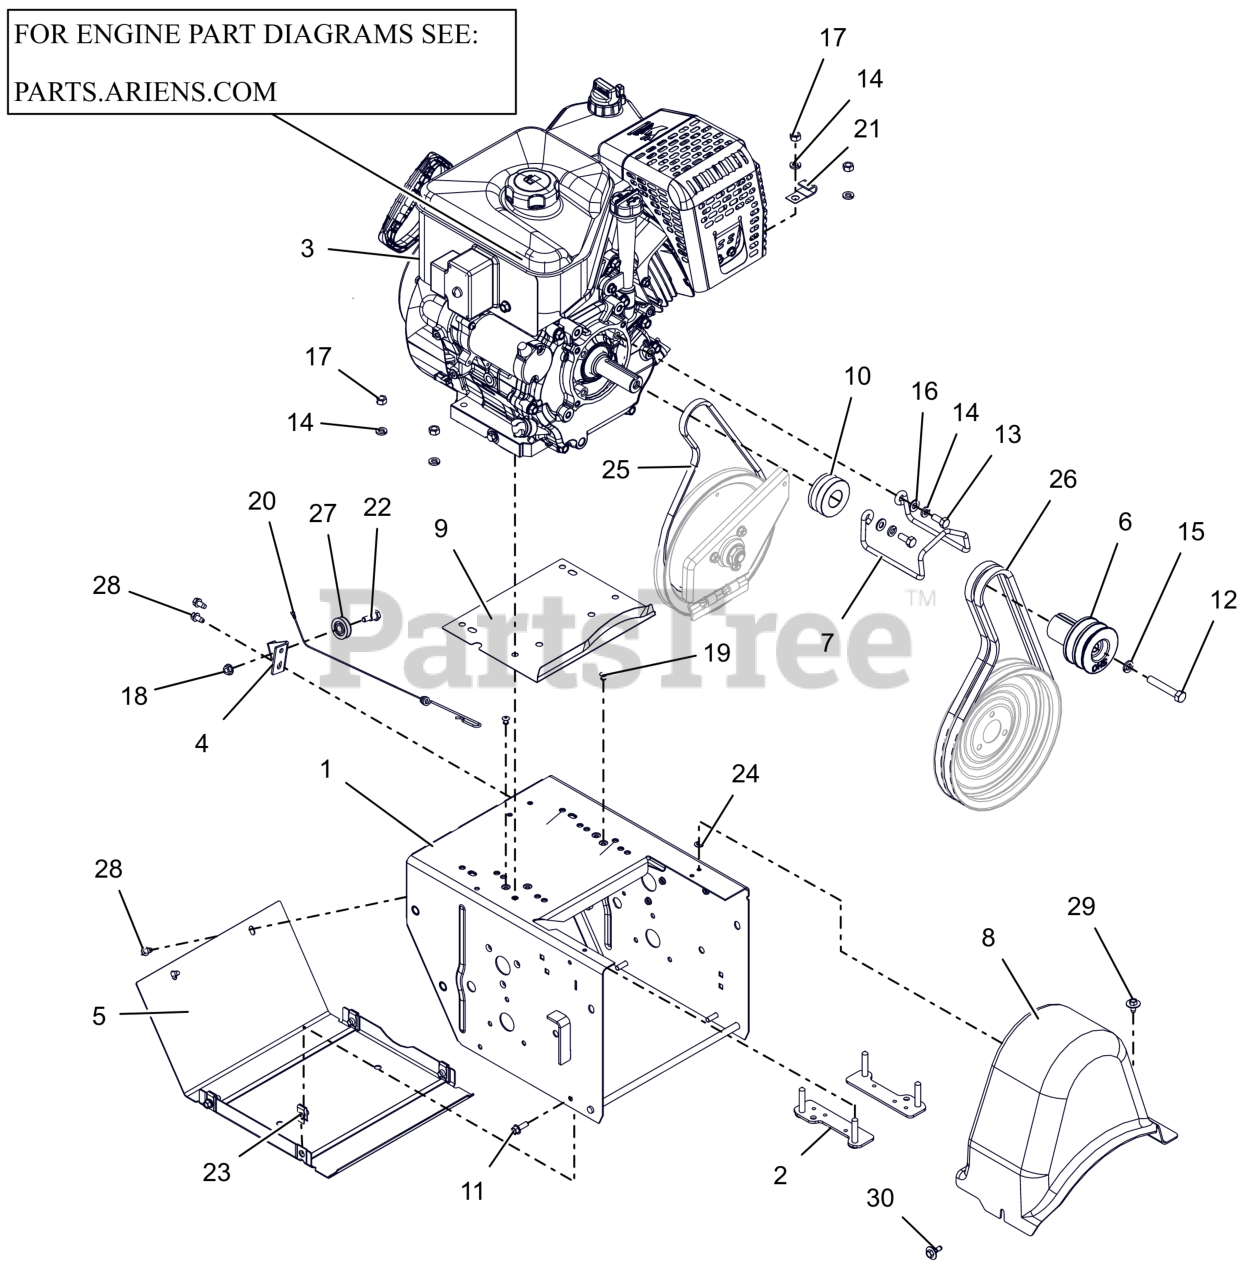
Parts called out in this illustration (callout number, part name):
1	FRAME, MAIN - 14GA DELUXE (ORANGE)
2	STRAP, BOLT-LARGE
3	ENGINE, AX414 GEN3 120V/60W
4	BRACKET, CABLE PULLEY
5	COVER, BOTTOM
6	SHEAVE,ATTACHMENT-SHO 2 GRV
7	FINGER, BELT
8	COVER, BELT-LARGE
9	BAFFLE, WATER - LARGE BLOCK
10	SHEAVE, TRACTION (KEYLESS)
11	BLT, HWH .25-20X.75 G5 ZCC
12	BLT, HEX .38-24X2.25 G5 ZCC
13	BLT, HEX .31-24X.750 G5 ZCC
14	WSHR, LK-HVY .312X.097 ZCC
15	WSHR,LK-REG .375X.094 ZCC
16	WSHR,FLT .344X.688X.065 ZCC
17	NUT, HEX .312-18 ZCC
18	NUT-LK-TOP-FLG .250-20 GF ZCC
19	RVT, POP .1875 ZCC
20	CABLE, LOWER TRACTION,SS & PRO
21	J-CLAMP
22	BOLT, SHLDR -.375 X .375 X .25-20
23	NUT-RTNR .25-20X.56
24	NUT-PUSH .25X.50 O.D.
25	V-BELT, 3L-WRAPPED
26	V-BELT, HA-RAW EDGE (SET)
27	PULLEY, CABLE
28	SCR-TAP .25-20X.50 HWH ZCC
29	SCR, TAP .25-20X.50 LG HWH ZCC
30	SCR-TAP .25-20X.5 CAPTIVE
